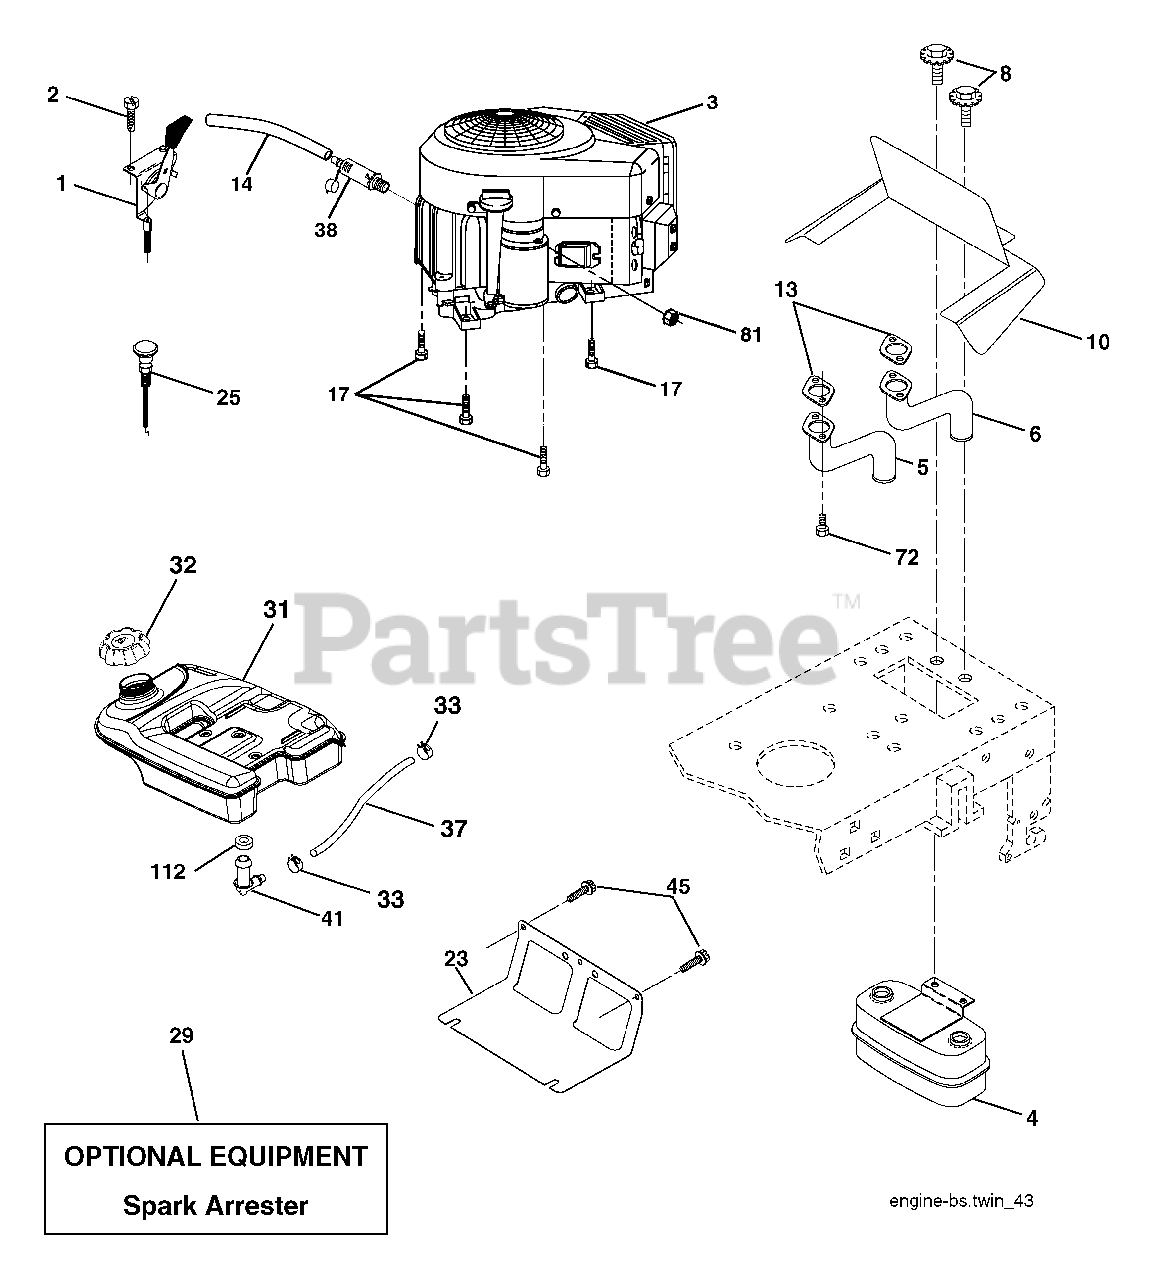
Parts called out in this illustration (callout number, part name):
1	Control Throttle
2	Screw Hex Thd Cut 1/4-20 x 1/2
5	Exhaust Tube LH
6	Exhaust Tube RH
8	Bolt 5/16-18 unc x 3/4
10	Shield Heat Muffler
14	Tube Drain Oil Easy
17	Screw 3/8-16 x 1-1/2
23	Shield Browning/Debris Guard
25	Control Choke
29	Kit Spark Arrestor (Flat Scrn)
32	Cap Asm Fuel
33	Clamp Hose Black
37	Line Fuel
38	Plug Drain Oil Easy
41	Stem Tank Fuel
45	Screw Hex Wsh Thdr 3/8-16 x 3/4
81	Nut Keps Hex 1/4-20 Starter Nut
112	Bushing
